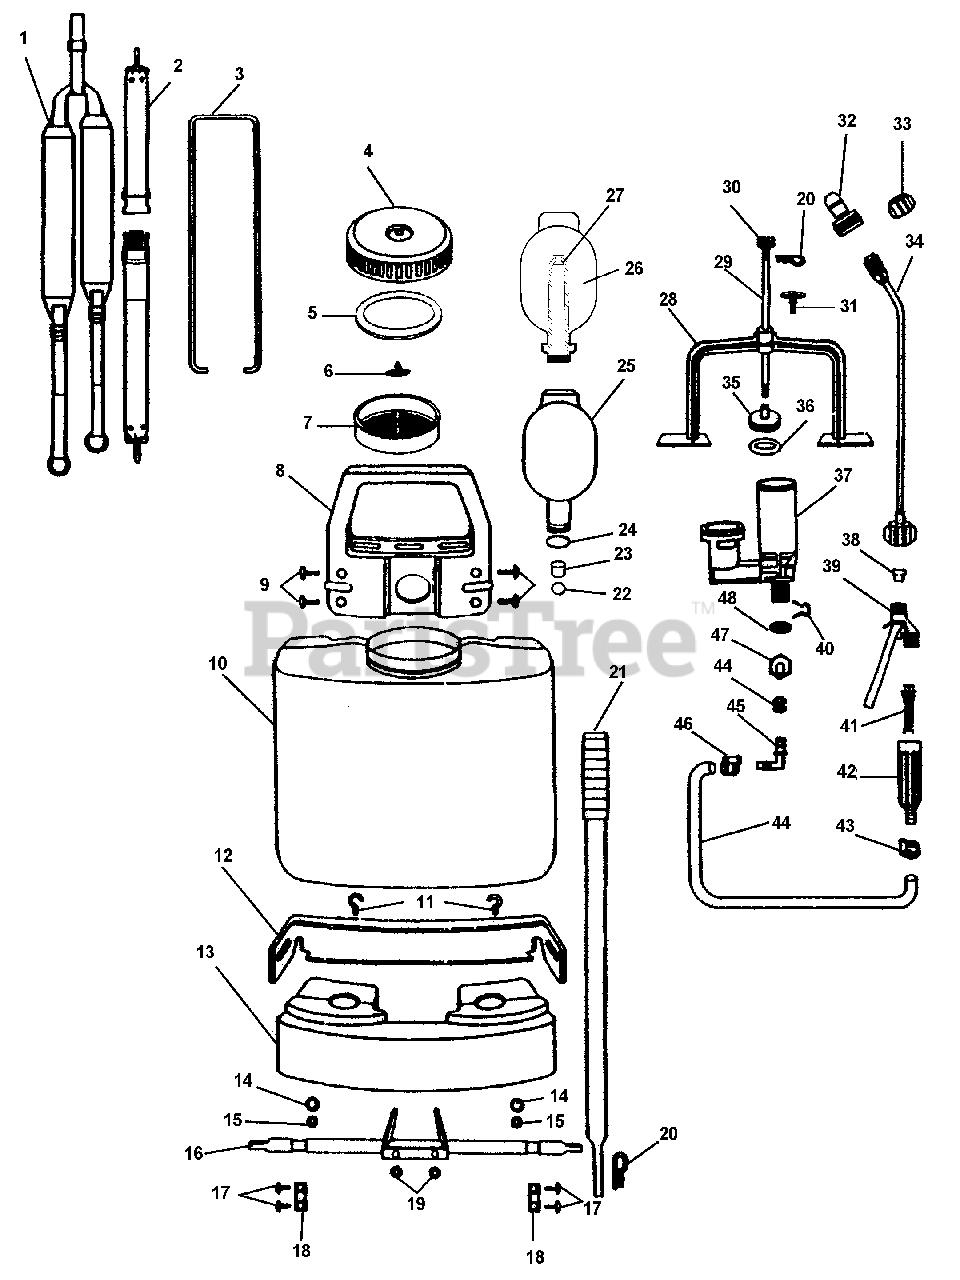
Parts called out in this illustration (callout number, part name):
1	HARNESS ASSY
2	WAIST BELT
3	ROD, CONNECTING
4	FILL CAP
5	COVER, GASKET
6	VALVE, CHECK
7	STRAINER BASKET
8	HANDLE, CARRY
9	SCREW
10	TANK, 5 GAL. (W/METAL NUT)
10	TANK, 5 GAL. (W/POLY NUT)
11	HOOK BOLT
12	LUMBAR SUPPORT
13	BASE
15	LOCKNUT
16	DRIVE ROD ASSY
18	RETAINER BRACKET
19	PUSHNUT
20	PIN - HITCH
21	PUMP HANDLE ASSY
22	VALVE, BALL
23	CHECK CAP (MANIFOLD)
24	O-RING
25	RESERVOIR ASSY - HIGH PRESSURE
26	RESERVOIR ASSY - LOW PRESSURE
27	BLADDER, LOW PRESSURE
28	AGITATOR
29	PLUNGER ROD (5 GAL. UNIT) FOR ASSY
31	GROMMET
32	NOZZLE (PLASTIC) STD
33	NOZZLE, FAN SPRAY
34	EXTENSION, CURVED - 24" -- BRASS
37	PUMP & MANIFOLD (ONLY W/METAL NUT) FOR ASSY
38	SEAT, VALVE
39	SHUT OFF ASSY - VITON
42	HANDLE
43	CLAMP, HOSE
44	HOSE, 56" EDPM FOR ASSY
45	FITTING ASSY (W/METAL NUT)
45	PUMP FITTING (W/POLY NUT) FOR ASSY
46	O-RING
47	NUT, HOSE FITTING (POLY NUT)
48	O-RING KIT
48	PUMP GASKET ASSY
